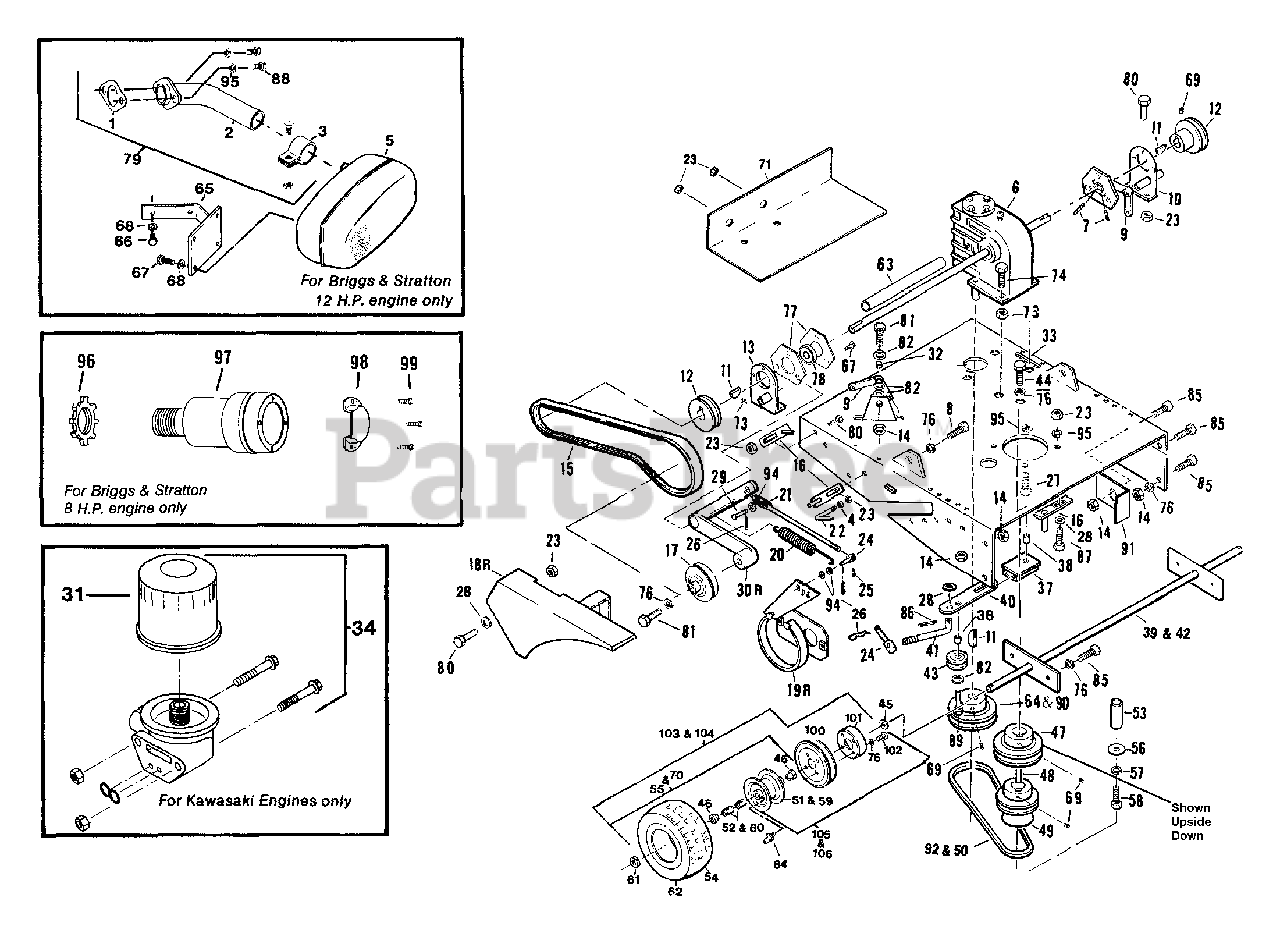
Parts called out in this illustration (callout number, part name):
1	Exhaust Gasket
2	Exhaust Tube Assy
3	Muffler Clamp w/Bolt & Nut
4	5/16"-18 Whizlock Nut
5	Super Lo-Tone Muffler
6	Worm Gear Reduction Box
7	#10-32x1/4" Nyloc Knurled Cup Point Set Screw
8	3/8"-16x1-1/4" Hex Hd. Cap Screw
9	Bell Crank
10	Bracket Support-Left
11	Woodruff Key #61/605
12	Pulley w/Set Screw (P/N 76956)
13	Bracket Support-Right
14	3/8"-16 Nyloc Hex Nut
15	Cog Belt
16	Belt Guide
17	Idler Pulley
18R	Fender-Right
19R	Brake Assy: Right
20	Extension Spring
21	Forward Motion Linkage
22	Scraper
23	5/16"-18 Nyloc Hex Nut
24	Adjustment Swivel-Short
25	"S" Hook
26	#2 Hairpin Cotter
27	5/16"-18x2" Hex Hd. Cap Screw-Grade 5 (Briggs)
27	M8x125x50 Metric Hex Hd. Cap Screw-Grade 5 (Kaw)
28	5/16" Std Flat Washer (Briggs & Stratton Engine Only)
28	5/16" Std Flat Washer (Kawasaki Engine Only)
29	Adjustment Swivel-Long
30R	Idler Arm-Right
31	Oil Filter (Kawasaki Engine Only)
32	Powdered Metal Bearing
33	Rear Deck w/Decals
34	Oil Filter Kit (Kawasaki Engine Only)
37	Bracket Slide
38	Spacer
39	Axle Assembly (36" & 48")
40	Slide Bar
41	Variable Adjustment Rod
42	Axle Assembly (32" Only)
43	PULLEY, Idler, 3/8" ID, 2.75" OD, 7/8" Wide
44	3/8"-16x2" Hex Hd. Cap Screw-Grade 5
46	Flange Bearing
47	Pulley w/Set Screws (P/N 76956)
48	1/4" Sq. x 5" Machine Key
49	Variable Speed Pulley w/Set Screw (P/N 76956)
50	Transmission Belt (32" & 36")
51	Wheel/Flange Assy (36" & 48")
52	Roller Bearing (36" & 48")
53	Engine Shaft Spacer
54	2 Ply Turfmaster Tire (36" & 48")
55	Tire Assy w/Brgs (36" & 48")
56	7/16" Std. Flat Washer
57	7/16" Lock Washer
58	7/16"-20x3-1/2" Hex Hd. Cap Screw-Grade 5 (Briggs)
58	M10x1.5x90 Metric Hex Hd. Cap Screw Grade 5 (Kawasaki Engine Only)
59	Wheel/Flange Assy (32" Only)
60	Roller Bearing (32" Only)
61	7/8" Clamp Collar
62	2 Ply Turfmaster Tire (32" Only)
63	Transmission Shaft Cover
64	32"-36" Transmission Pulley w/Set Screws (P/N 76956)
65	Muffler Bracket
66	1/4"-20x3/4" Hex Hd. Cap Screw-Grade 5
67	1/4"-20x5/8" Hex Hd. Cap Screw
68	1/4" Lock Washer
69	5/16"-18x3/8" Set Screw
70	Tire Assy w/Brgs (32" Only)
71	Protective Cover
73	1/4"-20 Nyloc Hex Nut
74	1/4"-20x1" Hex Hd Cap Screw
76	3/8" Lock Washer
77	Bearing Flange
78	Bearing w/attached Collar & 2 Set Screws (P/N 77679)
79	Exhaust Tube Kit
80	5/16"-18x3/4" Hex Hd. Cap Screw
81	3/8"-16x1-3/4" Hex Hd. Cap Screw-Grade 5
82	3/8" Std. Flat Washer
84	1/4"-28 Straight Zerk
85	3/8"-16x1" Hex Hd. Cap Screw-Grade 5
86	3/32" x 1/2" Cotter Pin
87	5/16"-18x1-3/4" Hex Hd. Cap Screw-Grade 5 (Briggs & Stratton Engine Only)
87	M8x1.25x25 Metric Hex Hd. Tap Bolt-Grade 5 (Kawasaki Engine Only)
88	5/16"-18x3/4" Hex Hd. Cap Screw-Grade 5
89	3/8"-16x2-1/4" Hex Hd. Cap Screw-Grade 5
90	48" Transmission Pulley w/Set Screws (P/N 76956)
91	Rod Stop (32" & 36")
92	Transmission Belt (48" Only)
94	Brake Linkage Washer
95	5/16" Lock Washer
96	Locking Ring
97	Round Lo-Tone Muffler
98	Side Out Deflector
99	Screw
101	Brake Drum
102	3/8"-24x5/8" Hex Hd. Cap Screw-Grade 5
103	Wheel/Tire Assy Complete (32" Only)
104	Wheel/Tire Assy Complete (36" & 48")
105	Wheel w/Sheave and Drum Assy (32" Only)
106	Wheel w/Sheave and Drum Assy (36" & 48")
